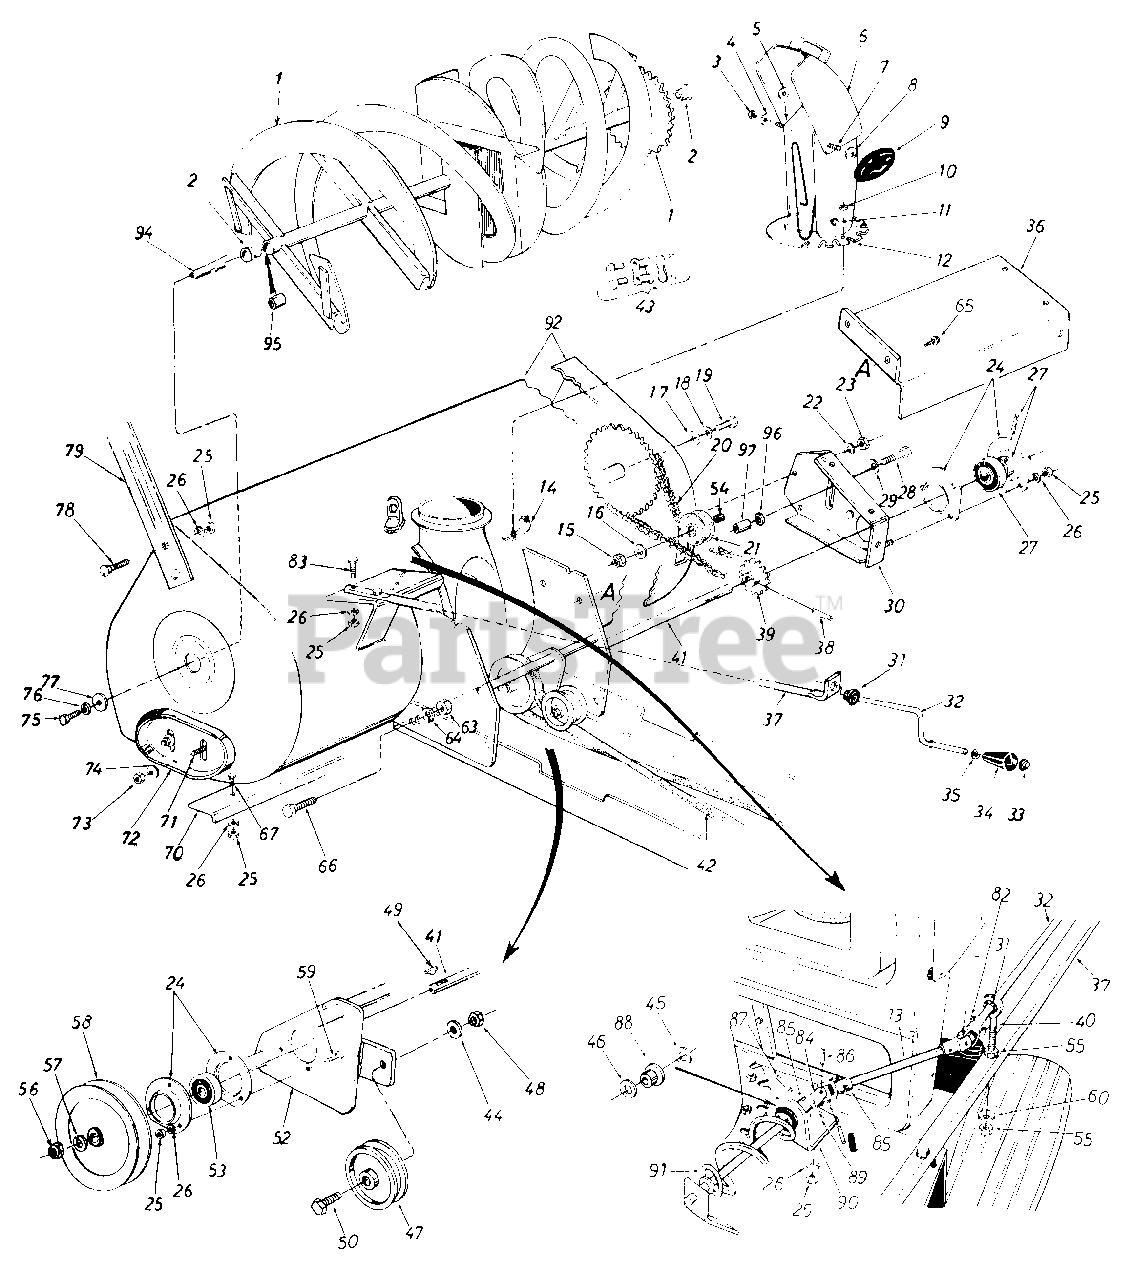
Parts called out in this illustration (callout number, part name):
1	Spiral Ass'y.
2	Flange Bearing
3	Hex Cent. L.-Nut 5/16-18 Thd.
4	Belleville Wash. 3/8" I.D.
5	Flat Washer 3/8" I.D.
6	Top Chute Ass'y.
7	Carriage Bolt 5/16-18 x .62" Lg.
8	Belleville Wash. 3/8" I.D.
9	Hand Knob
10	Hex Cent. L.-Nut 1/4-20 Thd.
11	Push Cap .188" Dia. Rod
12	Chute Ass'y.
13	Chute Crank Extension Rod
14	3 Chute Flange Keeper Ass'y.
15	L.-Nut 3/8-16 Thd
16	Fl.-Wash.
17	Fl.-Wash.
18	Belleville Wash.
19	Hex Bolt 1/2-13 x 1.00" Lg.
20	#420 Chain 1/2" Pitch x 77 Links
21	Plastic Idler 2.00" O.D.
22	L.-Wash. 1/4" I.D.
23	Hex Nut 1/4-20 Thd.
24	Bearing Housing
25	Hex Nut 5/16-18Thd.
26	L.-Wash. 5/16" I.D.
27	Self-Aligning Bearing
28	Hex Bolt 3/8-16 x 1.75" Lg.
29	Belleville Wash. 3/8" I.D.
30	Chain Guard Ass'y.
31	Nylon Bushing
32	Chute Crank .375 Dia. x 33" Lg.
33	Push Nut 3/8" Rod
34	Knob 3/8" Dia. Hole
35	FlatWasher
36	Drive Shaft Cover
39	14 Teeth Sprocket Ass'y.
40	Eyebolt5/16-18 x 3.0" Lg.
41	Drive Shaft
42	"V"-Belt 1/2" x 88" Lg. (Kevlar)
43	Master Link for #420 Chain
44	L.-Wash. 3/8" I.D.
45	Fl.-Wash. .385 I.D. x .62" 0. D.
46	Fl.-Wash. .390 I.D. x 1.50" O.D.
47	Fl.-Idler with Flanges
48	Hex Jam L.-Nut 3/8-26 Thd.
49	#61 Hi-Pro Key
50	Hex Bolt 3/8-16 x 1.50" Lg.
52	Spiral Housing Ass'y.
53	Self-Aligning Bearing
54	Sleeve Bearing .50" I.D.
55	Hex Nut 5/16-18 Thd.
56	Hex Nut 3/4-10 Thd.
57	L.-Wash. 3/4" I.D.
58	"V"-Pulley .750" I.D. x 6.00:" O.D.
59	Hex Sems Bolt 5/16-18 x .75" Lg.
60	Bell Wash. .345" I.D. x .88" 0. D.
63	Hex L.-Nut 1/2-20 Thd.
64	L.-Wash. 1/2" I.D.
65	Hex Wash. Hd. Tap Scr. 1/4-20 x.50" Lg.
66	Hex BoIt 1/2-20 x 1.25" Lg.
67	Carriage Bolt 5/16-18 x .62"
72	Skid Shoe
73	Hex Nut 3/8-16 Thd.
74	BellevilleWash.3/8" I.D.
75	Hex Bolt 1/2-13 x 1.00" Lg.
76	BellevilleWash. 1/2" I.D.
77	Fl.-Wash.
78	Carriage Bolt 5/16-18 x .62 " Lg.
79	Drift Cutter
82	Cotter Pin
83	Hex Bolt 5/16-18 x 1.50" Lg.
84	Joint Block
85	Joint Bracket Ass'y.
86	Spring Pin Roll 3/16" Dia. x .75" Lg.
87	Spring Pin Foll 1/8" Dia. x .75" Lg. .75" Lg.
88	Nylon Bushing
89	Carriage Bolt 5/16-18 x .62
90	Chute Crank Bracket
91	Chute Crank Ass'y.
92	Spiral Housing Ass'y.
95	Sleeve Bearing
96	Flat Washer
97	Idler Spacer
